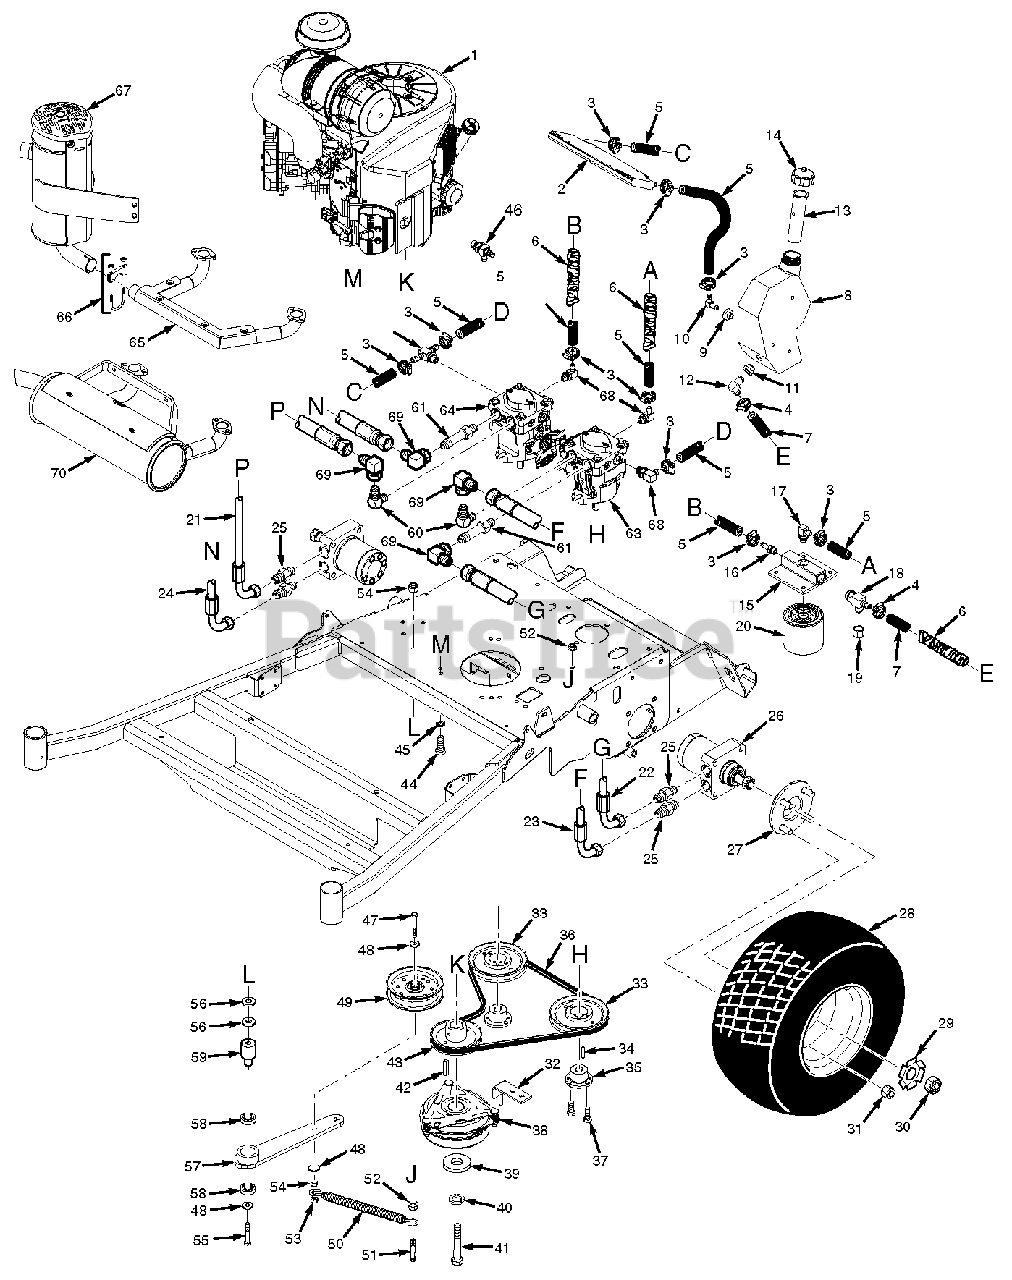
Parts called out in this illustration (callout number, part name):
1	Engine, 23hp Kawasaki FX730V
1	Engine, 25hp Kawasaki FX801V
1	Engine, 26hp Kohler ECV749 - EFI
2	Cooler, Transmission (52V/61V)
3	Clamp, .69 Max Dia.
4	Clamp, .87 Max Dia.
5	Hose, 3/8 Pushlock
6	Heatshield, Flexible
7	Hose, 1/2 Pushlock
8	Hydraulic Tank Assy.
9	Bushing, .56 Dia, Viton
10	Fitting, 90 Degree - .38 Hose
11	Bushing, .78 Dia. Viton
12	Fitting, 90 Degree - .50 Hose
13	Insert, Filler Neck
14	Cap, Hydraulic Tank
15	Filter Head
16	Fitting
17	Elbow, 90 Degree
18	Tee Fitting, 3/4 O-Ring
19	Cap, 3/4" JIC
20	Oil Filter
21	Hose Assembly
22	Hose Assembly
23	Hose Assembly
24	Hose Assembly
25	Fitting, Union 1/2 x 5/8
26	Wheel Motor
27	Wheel Hub
28	Wheel Assembly
28	Rim w/Valve Stem
28	Tire, 20 x 10.5-8 4-Ply
29	Lockwasher, Wheel Motor
30	Hex Castle Nut, 3/4-28
31	Wheel Nut
32	Anti-Rotation Bracket
33	Pulley, 5.45 OD - Tapered Bore
34	Key, 5 x 5 x 25mm
35	Tapered Hub, 15mm Bore
36	Belt, Pump Drive
37	Bolt, Hex Head 1/4-20 x 1" Gr. 8
38	Clutch w/Tag
39	Flatwasher, 7/16-.469 x 1.75 x .25
40	Lockwasher, 7/16" Spring
41	Bolt, Hex Head 7/16-20 x 2-1/4" Patch
42	Key, 1/4 x 1/4 x 3-1/2"
43	Pulley, 4.75 OD - 1.125" Bore
44	Bolt, Hex Head 3/8-16 x 1-1/4"
45	Lockwasher, 3/8" Spring
46	Oil Drain
47	Bolt, Hex Head 3/8-16 x 2-3/4"
48	Flatwasher, 3/8-.391 x .938 x .105 HD
49	Pulley, 4-1/2" Idler
50	Spring, Transmission
51	Bolt, Hex Head 3/8-16 x 3"
52	Nut, Serrated Flange 3/8-16
53	Nut, Center Lock 3/8-16
54	Nut, Elastic Stop 3/8-16
55	Bolt, Hex Head 3/8-16 x 3-1/4"
56	Flatwasher, 3/8-.375 x 1-1/2 x .059
57	Idler Arm Assy
58	Bearing
59	Idler Pivot, Long
60	Elbow, 90 Degree - 1/2 x 1/2
61	Fitting, Union 3/4-16 JIC x O-Ring
62	Tubing, Oil Drain
63	Pump, LH - 10cc w/Shock Valves (52)
63	Pump, LH - 12cc w/Shock Valves (61)
63	Pump, RH - 10cc w/Shock Valves (52)
64	Pump, RH - 12cc w/Shock Valves (61)
65	Exhaust Manifold, 29FX Kawasaki
66	Clamp, Muffler 1.25 Dia. Kawasaki
67	Muffler, 29FX Kawasaki
68	Elbow, 90 Degree
69	Elbow, 1/2 JIC Female to 1/2 JIC Male
70	Muffler, SVR-CV-EFI (Oxygen Sensor not included)
